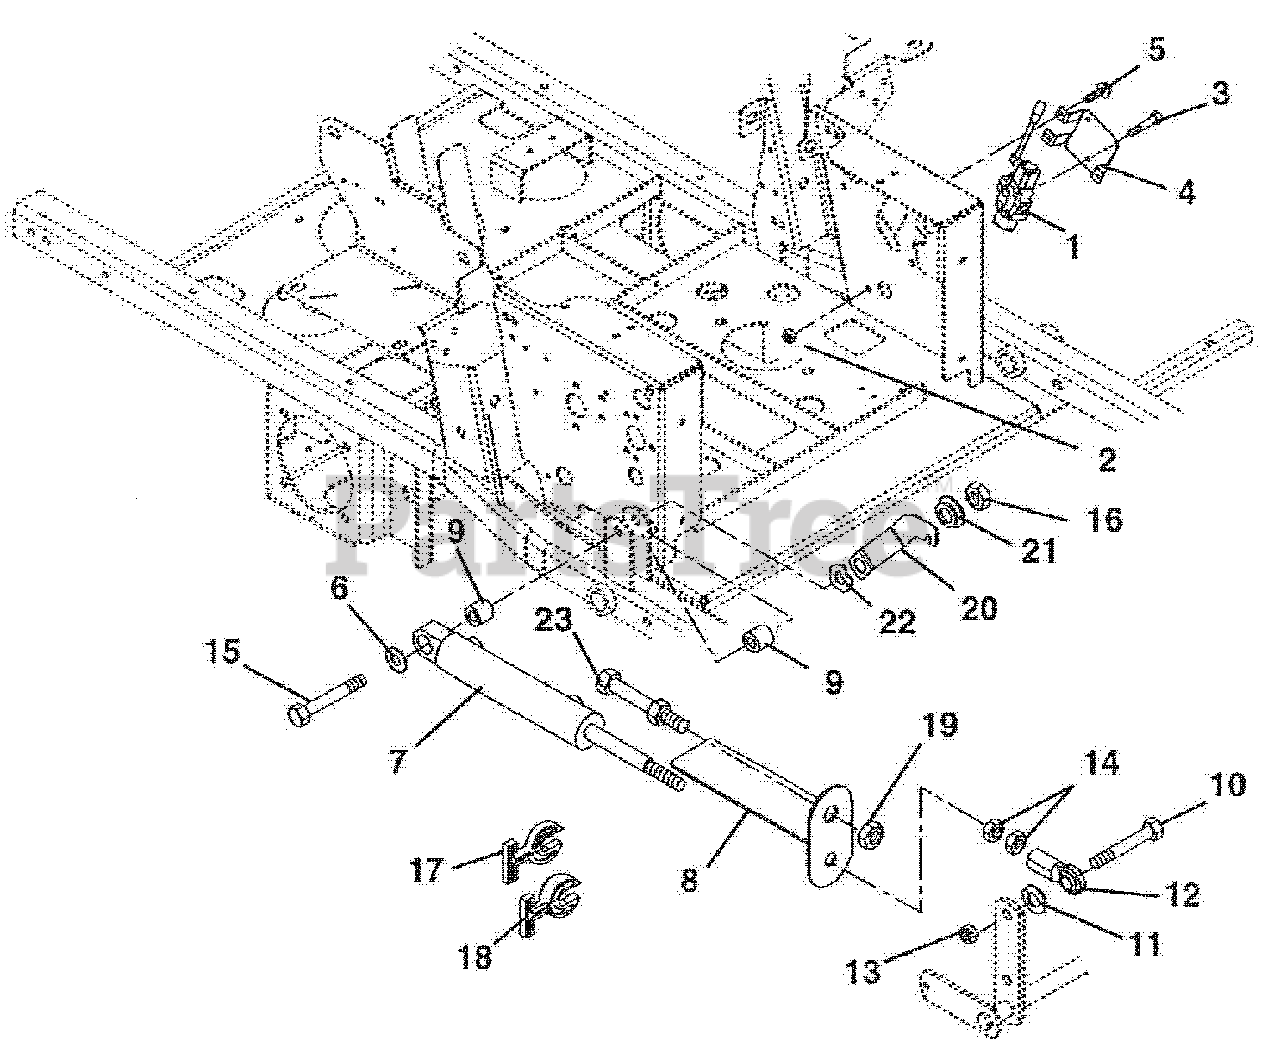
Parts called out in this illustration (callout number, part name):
1	Valve, Hydraulic
2	Nut, Locking Top Flange .31-18
3	Bolt, Hex .31-18 x 2.5 Grade 5
4	Bracket, Valve Mounting
5	Screw, Tapping .38-16 x .50 Hex Washer Head
6	Washer, Flat Steel .515 x 1.625 x .25
7	Cylinder, Hydraulic Lift
8	Strap, Cut Indicator / Guard
9	Bushing .516 x 1.00 x 1.05
10	Bolt, Hex .61-11 x 2.25 Grade 8
11	Washer, Lock .62 x .156
12	Rod End, Right Hand Female .625
13	Nut, Locking Center .62-11
14	Nut, Jam .625-18
15	Bolt, Hex .50-13 x 3.75 Grade 5
16	Nut, Locking Top Flange .50-13
17	Stop, Cylinder .34 Thick
18	Stop, Cylinder .68 Thick
19	Nut, Jam Center-Lock .75-16
20	Latch, Footboard
21	Bushing, Flange .515 x .75 x .275 x 1.12
22	Washer, Wave .076 x 1.12 x .08
